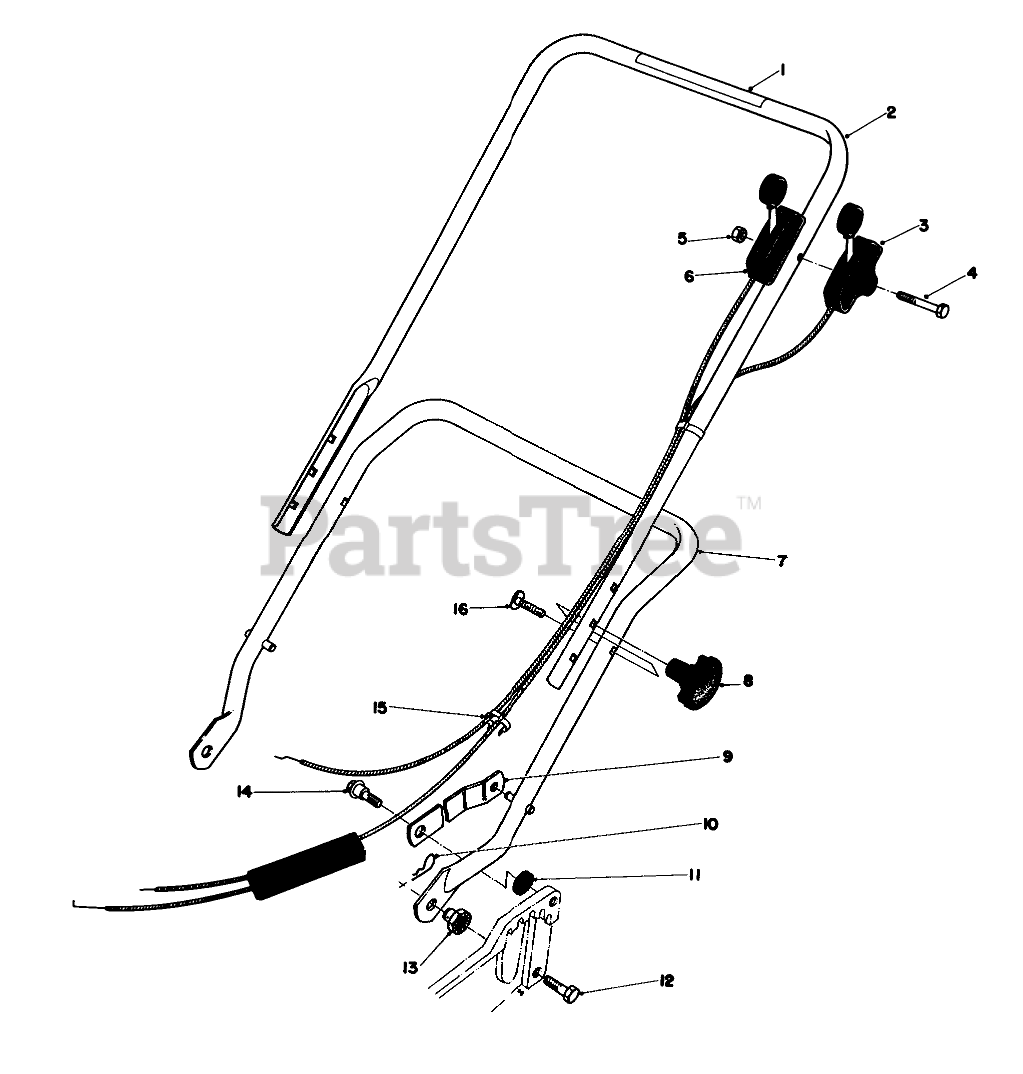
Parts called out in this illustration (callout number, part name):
1	Danger-Decal
2	Upper Handle
3	Traction Control
4	SCREW-HH
5	NUT-LOCK
6	Throttle Control
7	LOWER HANDLE ASM
9	HANDLE LATCH
10	PIN-COTTER, HAIR
11	HANDLE LATCH SPACER
12	SCREW-HH
13	HANDLE PIVOT NUT
14	SCREW-SHOULDER
15	BOWDEN CLIP
16	SCREW-HANDLE
